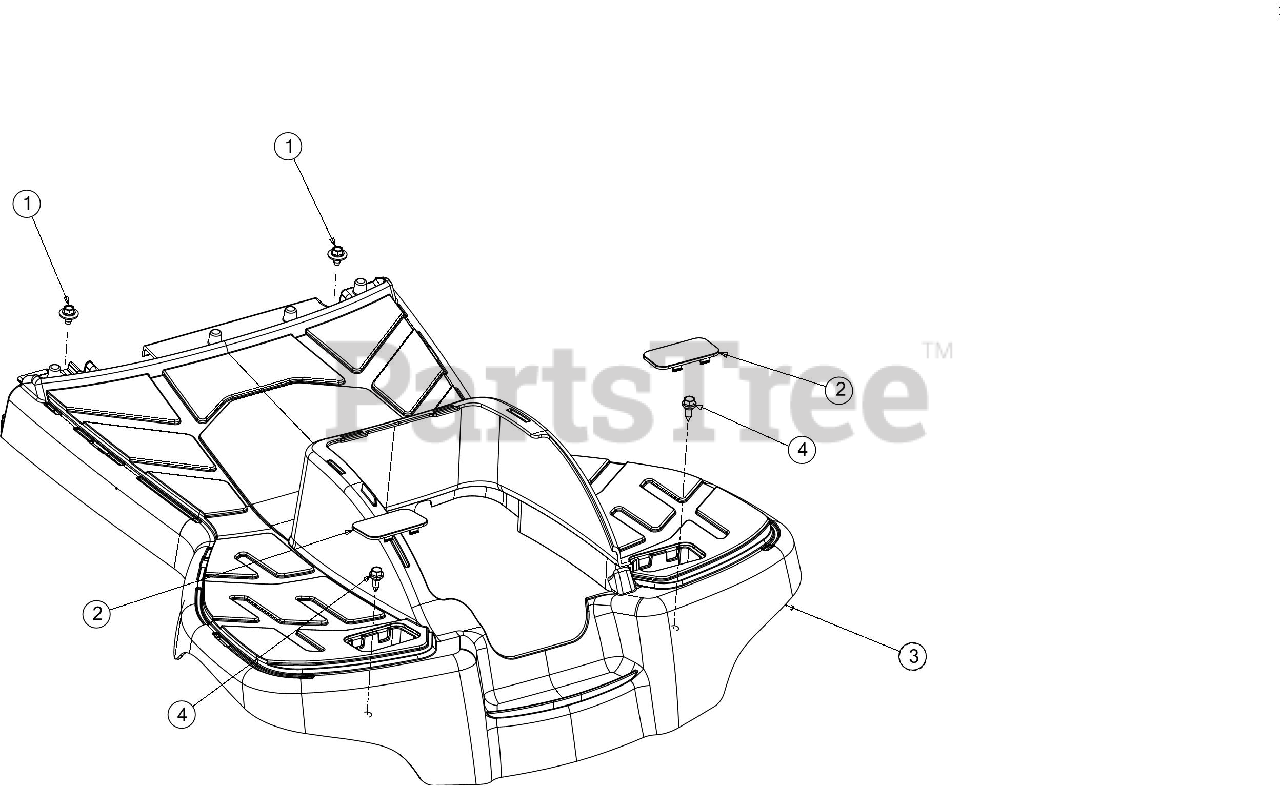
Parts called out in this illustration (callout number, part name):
1	SCREW 1/4-20 x .50
2	RUNNING BOARD PLUG
3	RUNNING BOARD
4	SHOULDER SCREW
